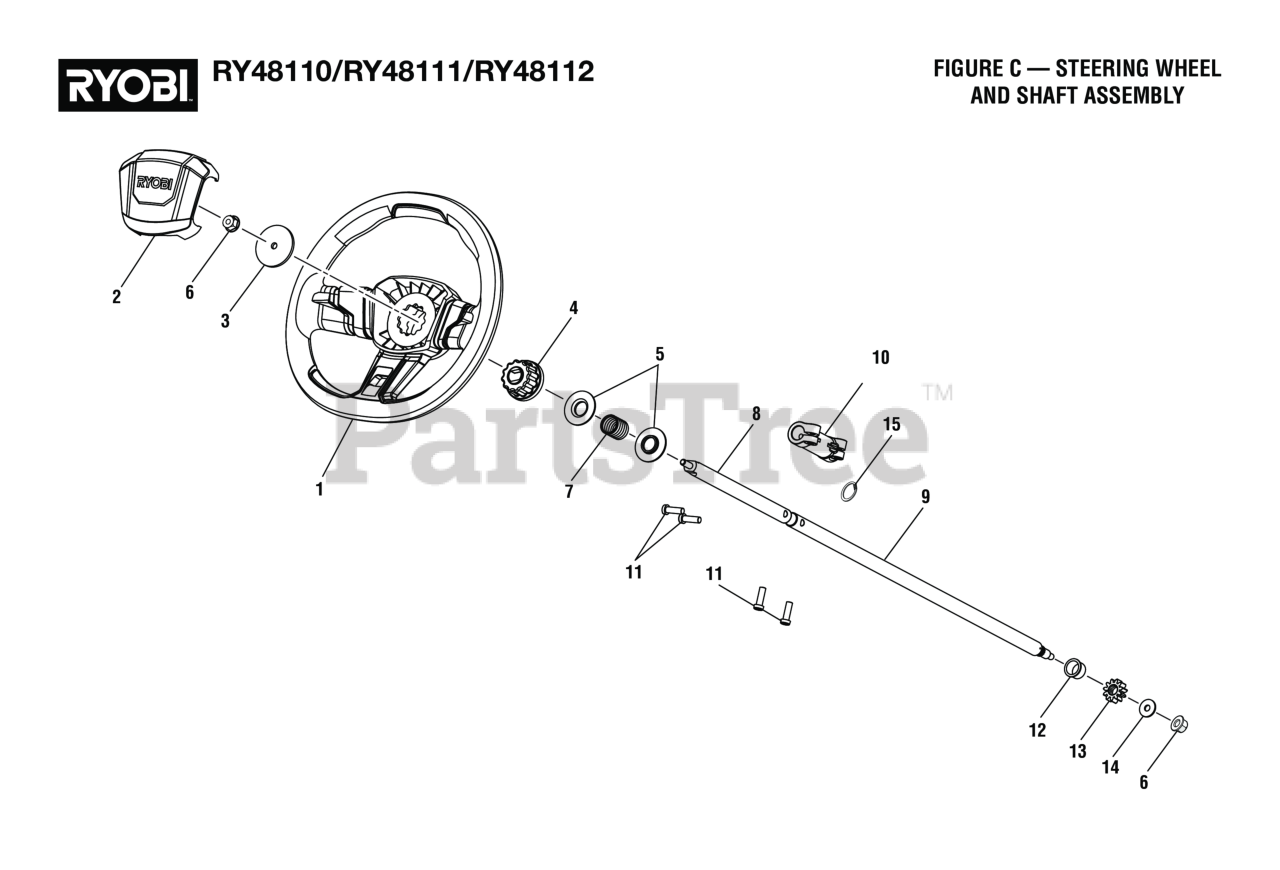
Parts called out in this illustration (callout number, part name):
1	Steering Wheel
2	Steering Wheel Cap
3	Washer Plate
4	Spline Collar
5	Spring Seat
6	Flange Nut (M8) (For Drive Motor Controller V)
7	Steering Shaft Spring
8	Upper Steering Shaft
9	Lower Steering Shaft
10	Steering Shaft Coupling
11	Screw (M8 x 25 mm, Soc. Hd.)
12	Flanged Bushing (19 x 22 x 15)
13	Steering Pinion Gear
14	Washer (OD 24 x ID8.4 x 2t)
15	Retaining Ring
